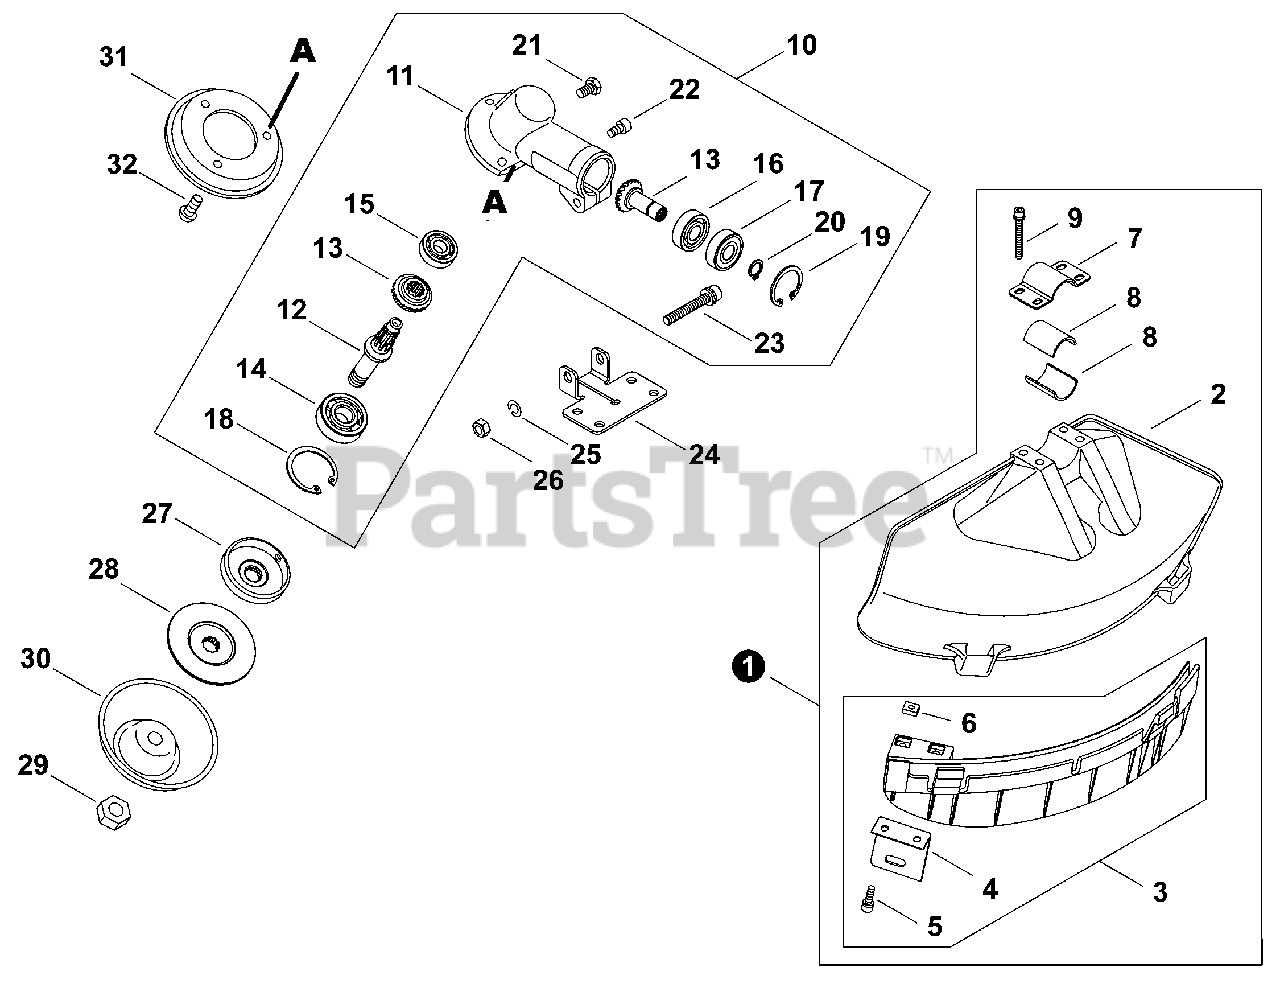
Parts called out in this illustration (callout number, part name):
1	DEBRIS SHIELD KIT
2	SHIELD, DEBRIS PLASTIC
3	DEBRIS SHIELD EXTENSION ASSY
5	BOLT 5×16
7	CLAMP, UPPER
8	SPACER 26
9	BOLT M5×45
10	GEAR CASE ASSY
11	CASE, GEAR
12	SHAFT, GEAR
13	GEAR SET, BEVEL
14	BEARING, BALL
15	BEARING, BALL
16	BEARING, BALL
17	BEARING, BALL
18	RING, SNAP
19	RING, SNAP
20	RING, SNAP
24	CLAMP, LOWER
25	WASHER, SPRING
27	PLATE, ADAPTOR - UPPER
28	PLATE, ADAPTOR - LOWER
29	NUT, LOCK - NYLON INSERT
30	ADAPTER, SAW
31	RETAINER, LOWER BLADE
